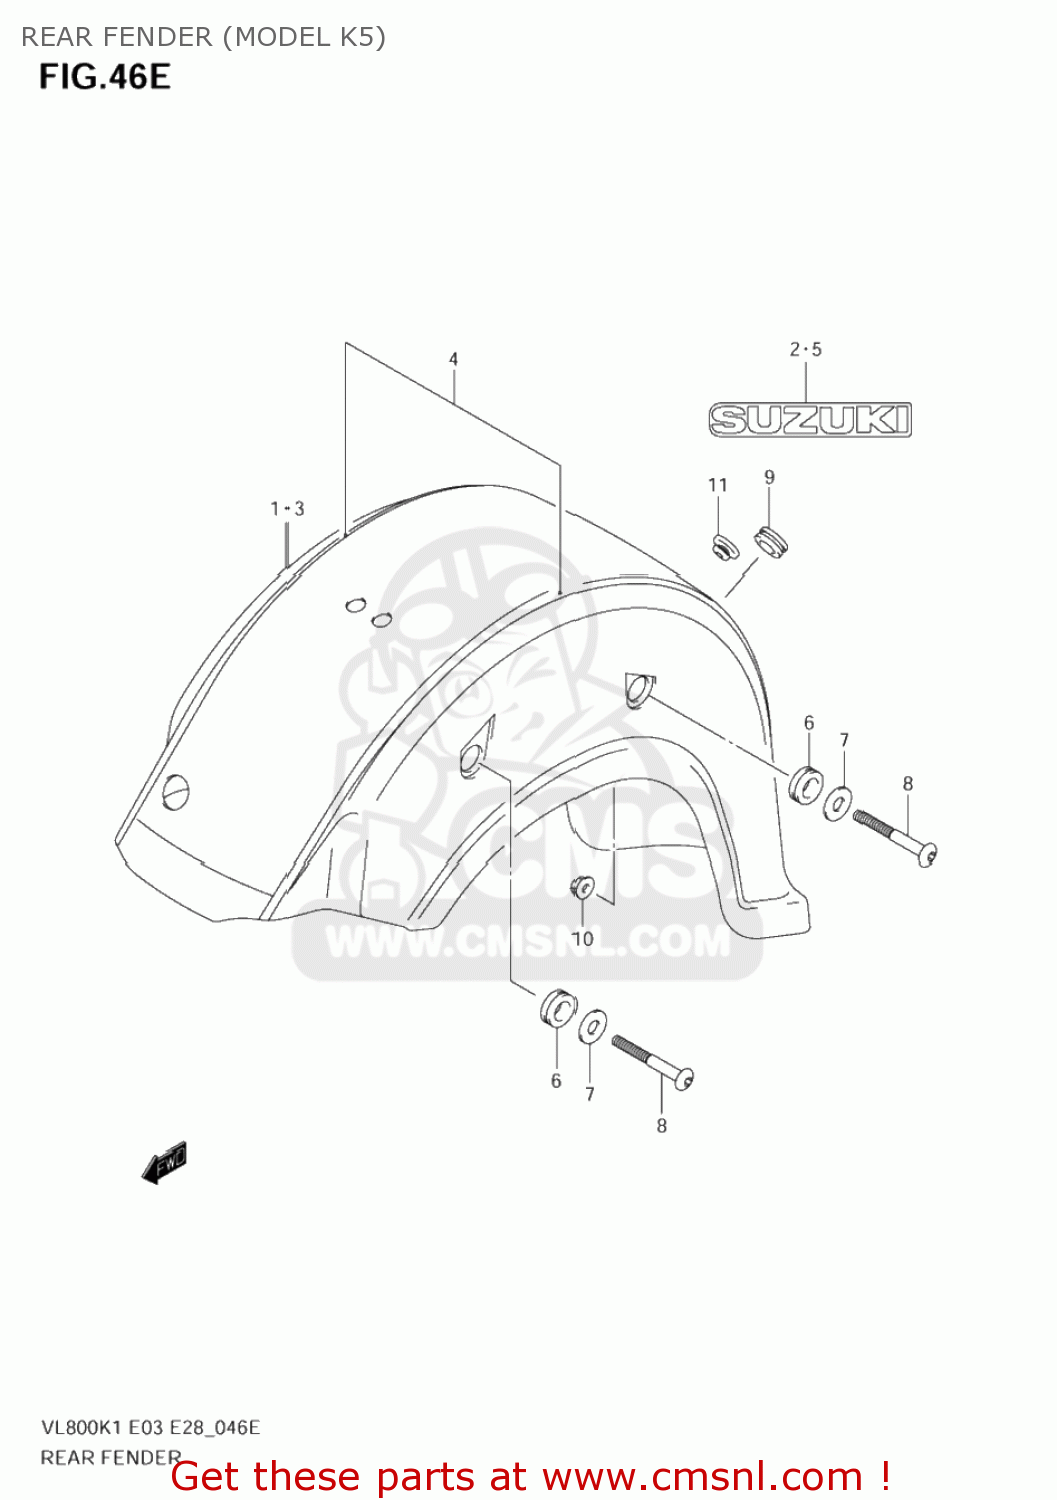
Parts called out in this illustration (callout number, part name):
1	FENDER,RR
2	EMBLEM,SUZUKI
3	FENDER,RR
4	TAPE SET,REAR
5	EMBLEM,SUZUKI
6	CUSHION,FRAME COVER UPR RR
7	WASHER(15.5X26X2.3)
8	BOLT,RR FENDER
9	CUSHION
10	NUT
11	CUSHION
